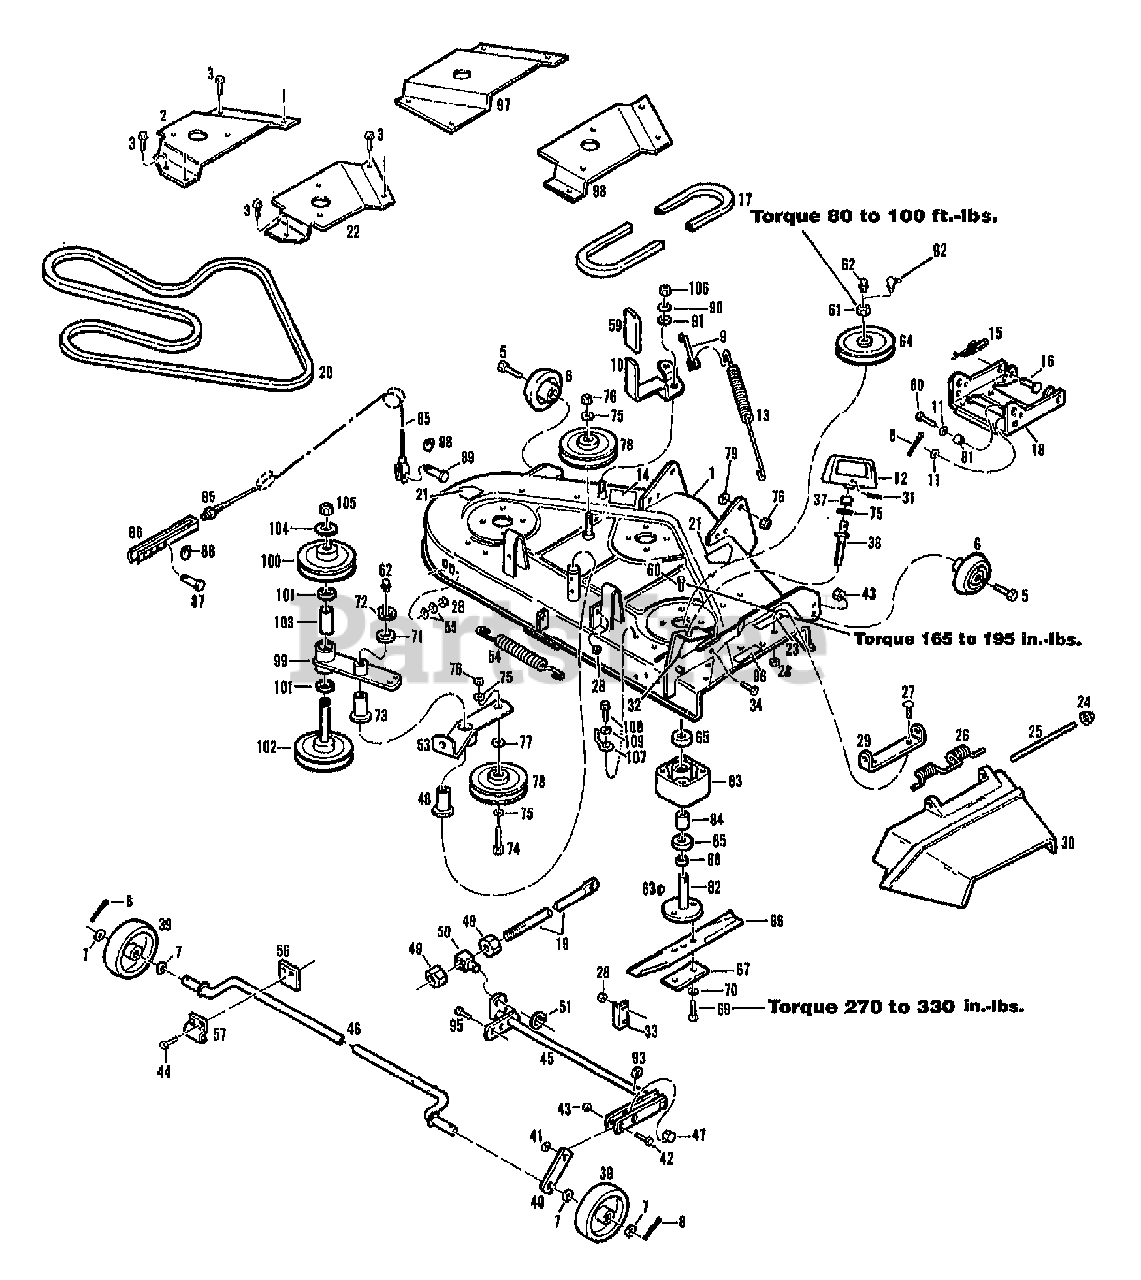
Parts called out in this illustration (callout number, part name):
1	ASSM-MOWER DECK W/DECALS {14000}
1	ASSM-MOWER DECK W/DECALS {14001}
2	COVER-BELT LH {14000}
2	COVER-BELT LH {14001}
3	SCR 1/4-20X.5 FL SELF TAP
5	SCR-SHLDR 3/8-16
6	WHEEL-GAGE
7	WASHER-1.38 X.765X .06 ZP
8	PIN-COTTER .120X1.25 ZP
9	ROD-IDLER
11	WASHER-.5 DIA
12	HANDLE-HEIGHT ADJ
13	SPRING-EXTENSION
14	DECAL-BELT DRIVE
15	RING-COTTER
16	PIN-CLEVIS .62X2.50 ZP
17	BELT-V
18	ASSM-MOWER SUPPORT
19	ROD-ADJUSTING
20	BELT-V {14000}
20	BELT-V {14001}
21	DECAL-OPEI CAUTION
22	COVER-BELT RH {14000}
22	COVER-BELT RH {14001}
23	DECAL-CUTTING LINE
24	NUT-PUSH 3/8 ZP
26	SPRING-TORSION
27	BOLT-CARR 5/16-18X.63 ZP
28	NUT-TOP/LK 5/16-18 ZP
30	DEFLECTOR-DISCHARGE
31	PIN-ROLL .188X1.0
32	DECAL-HEIGHT ADJUST
33	RETAINER-SHAFT
34	SCR-HH 5/16-18X.63 G5
37	SPACER-HANDLE
38	ROD-ADJUSTING
39	GAUGE-WHEEL
40	LINK-WHEEL SUPT
41	SPACER-.75X.39X.545
42	SCR-HH 3/8-16X1.5 G5 ZP
43	NUT-LOCK 3/8-16
44	SCR-HH 5/16-18X1.0 G5 ZP
45	ARM-HEIGHT ADJUST
46	SUPT-WHEEL SHAFT
47	PIVOT-ADJUSTING SCR
48	BEARING-FLANGE
49	NUT-HEX
50	BLOCK-PIVOT
51	RING-RETAINING EXT .694 ID
54	SPRING-EXT
55	WASHER-LOCK
56	PLATE-DOUBLER
57	SUPPORT-SHAFT
60	SCR-HFLK 5/16-18X.75
61	NUT-H/LK
62	FITTING-GREASE 1/4-28X2.00
63	KEY-WOODRUFF .188X.75
65	BEARING-BALL
66	BLADE-42" GRS DECK {14000}
66	BLADE-CUTTER {14001}
67	PLATE
68	WASHER N/A
69	SCR-HH 3/8-24X1.0 G5 ZP
70	WASHER-LK .375 @ DEPL
71	SHIM-WASHER
72	RING-RET. EXT .875 ID
73	FLANGE-BEARING
74	SCR-HH 1/2-13X2.0 G5 ZP
75	WASHER-FLAT .88X.5X.06 ZP
76	NUT-TOP LOCK 1/2-13 ZP
78	PULLEY-IDLER
79	WASHER
80	SCR-HH 1/2-13X1.25 G5 ZP
81	SPACER-TUBULAR
82	ASSM-BLADE SHAFT
83	HOUSING-SPINDLE
85	ASSM-CABLE(MOWER DECK)
86	YOKE
87	PIN-CLEVIS .5X1.437 ZP
88	RING-CIRCLE COTTER
89	PIN-CLEVIS .375 X .937 ZP
90	WASHER-.875X.390X.134
91	WASHER-FLAT 1.0X.516X.031 {14000}
91	WASHER-SHIM {14001}
92	FITTING-GREASE 90 DEGREE
93	WASHER-PLASTIC
95	SCR-HHC 5/16-18X.75 GR 5 ZP
96	DECAL-DANGER
97	COVER-BELT LH {14001}
98	COVER-BELT RH {14001}
99	ASSM-MOUNTING ARM
100	ASSM-SHEAVE & HUB
101	BEARING-BALL
102	ASSM-SHEAVE & SHAFT
105	NUT-TOP LOCK 1/2-13 ZP
106	NUT-H/LK 3/8-24
107	GUIDE-BELT {14001}
108	SCR-FLANGE 1/4-20X3/4 GR5 {14001}
109	WASHER-.75X.312X.065 ZP {14001}
